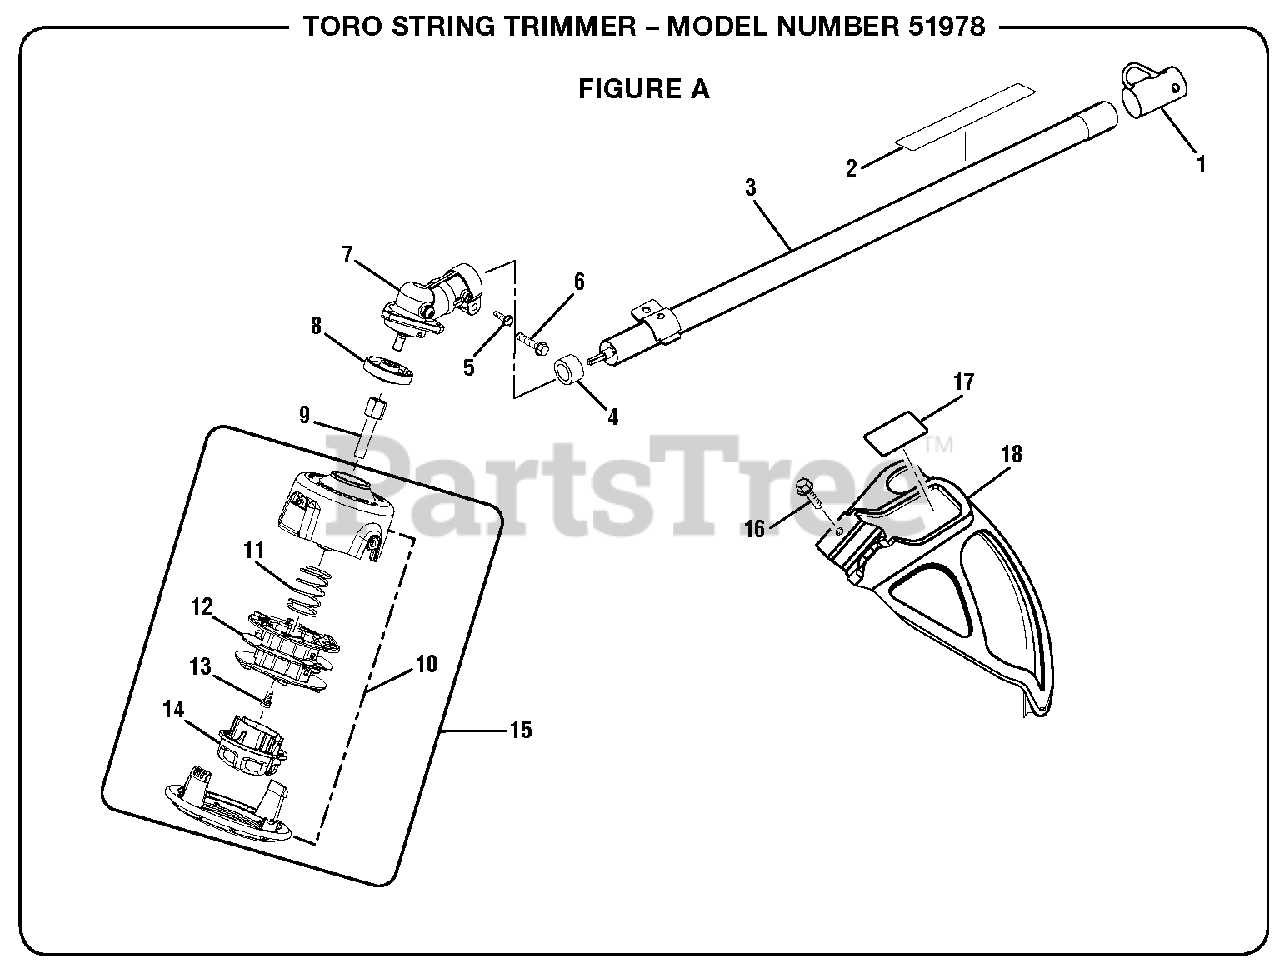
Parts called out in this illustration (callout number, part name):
1	Hanger Cap
2	Warning Label
3	Straight Shaft Assembly
5	Screw (10-24 x 5/8 in., Hex Washer Hd.)
6	Screw (1/4-20 x 1-1/4 in.)
7	Gear Head Assembly
8	Flanged Washer
9	Trimmer Head Shaft Adaptor
10	Stringhead Housing
11	Compression Spring
12	Spool
13	Bolt (5/16-18 x 1/2 in., L.H.)
14	Bump Knob
15	Trimmer Head Assembly
16	Screw (1/4-20 x 1-1/4 in., Hex Washer Hd.)
17	Grass Deflector Label
18	Grass Deflector Assembly
